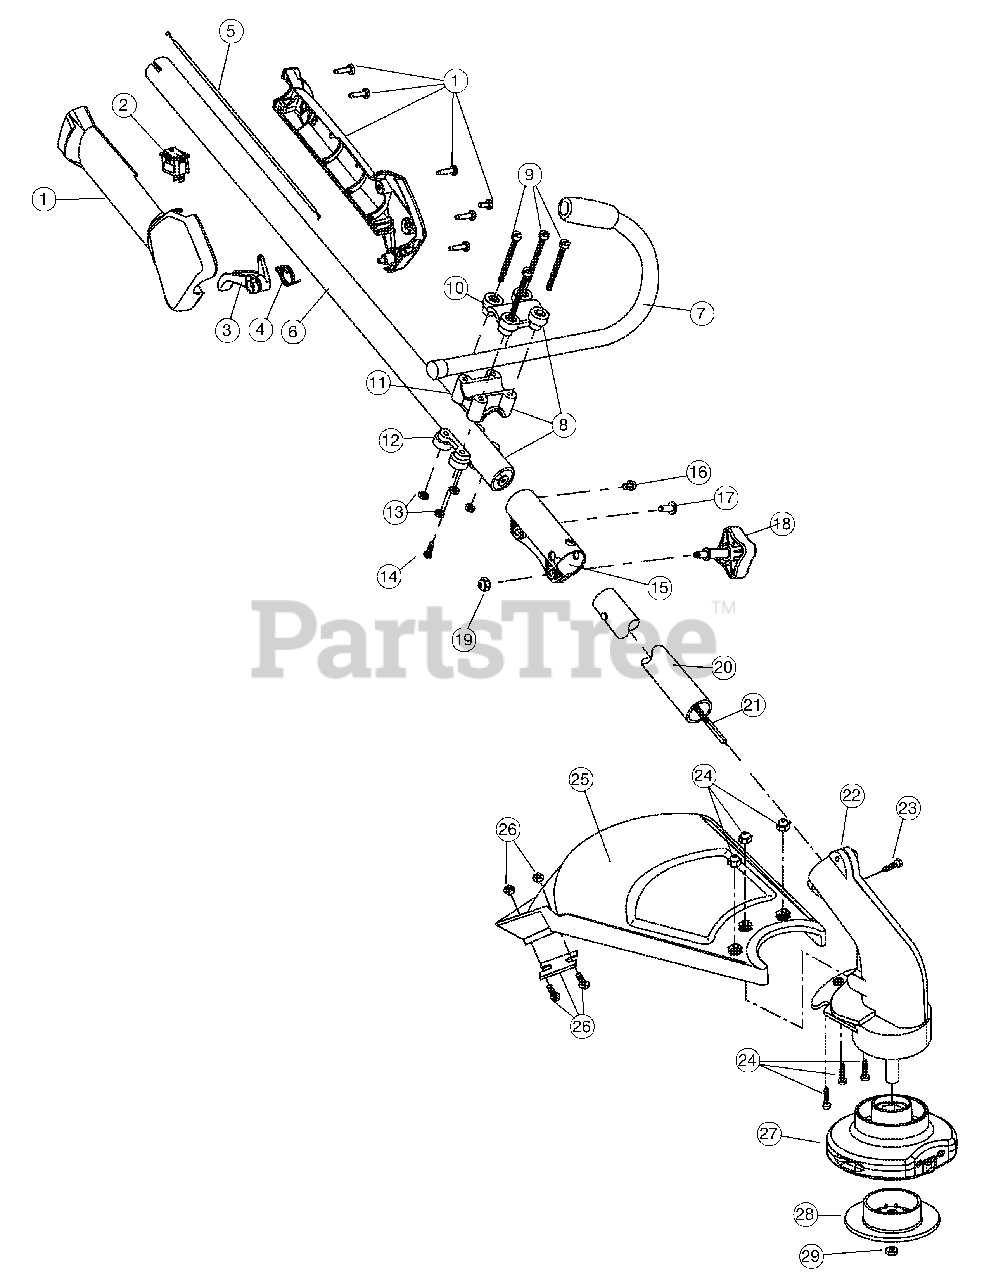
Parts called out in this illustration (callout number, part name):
1	Throttle Housing Assembly (includes 2-4)
3	Throttle Trigger
4	Throttle Trigger Spring
5	Throttle Cable
6	Upper Drive Shaft Housing Assembly
7	J-Handle Assembly
8	Handle Bracket Assembly (includes 9-14)
10	Upper Handle Clamp
11	Middle Handle Clamp
12	Lower Handle Clamp
14	Anti-Rotation Screw
15	Split Boom Coupler (includes 16-19)
18	Adjustment Knob (Includes 19)
19	Knob Retaining Nut
20	Lower Drive Shaft Housing Assembly
21	Lower Flexible Drive Shaft
22	Gearbox Assembly
23	Anti-Rotation Screw
24	Shield Mounting Hardware
25	Shield Assembly (includes 26)
26	Blade Assembly
27	Fixed Line Head Assembly (includes 28 & 29)
28	Glide Cap
29	Locknut
